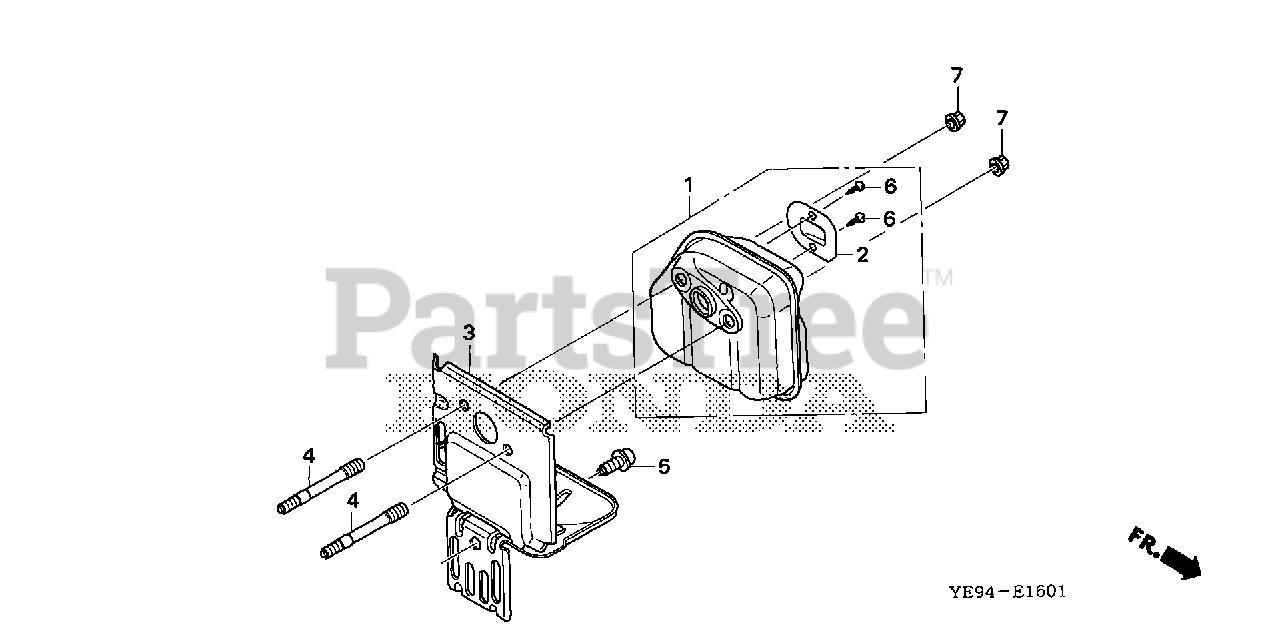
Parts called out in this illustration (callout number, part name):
2	ARRESTER, SPARK
3	GUIDE, AIR EX.
4	BOLT, STUD (5X52)
5	BOLT, SOCKET (5X10) (CT)
6	SCREW, TAPPING (4X6)
7	NUT, SELF-LOCK (5MM)
